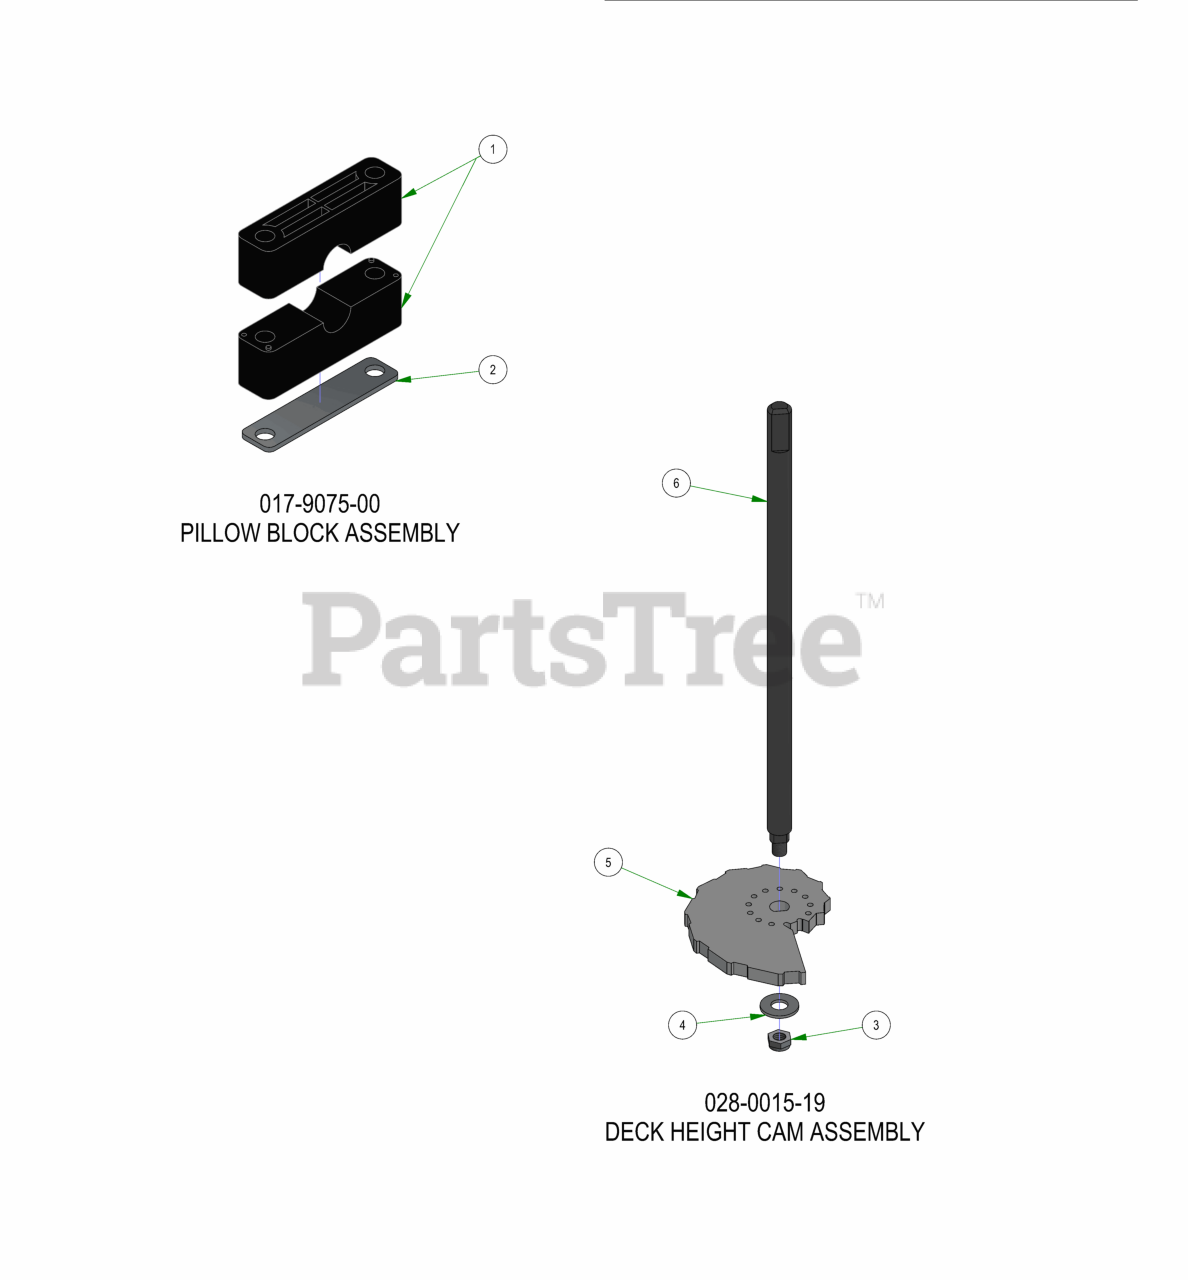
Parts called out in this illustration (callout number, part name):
1	Two Piece Pillow Block
2	Two Piece Pillow Block Strap
3	3/8-24 Nylon Insert jam locknut
4	3/8 FLAT WASHER USS (1" OD) ZINC
5	2019 Deck Height Cam
6	2019 Outlaw Gen2 Dial Rod
